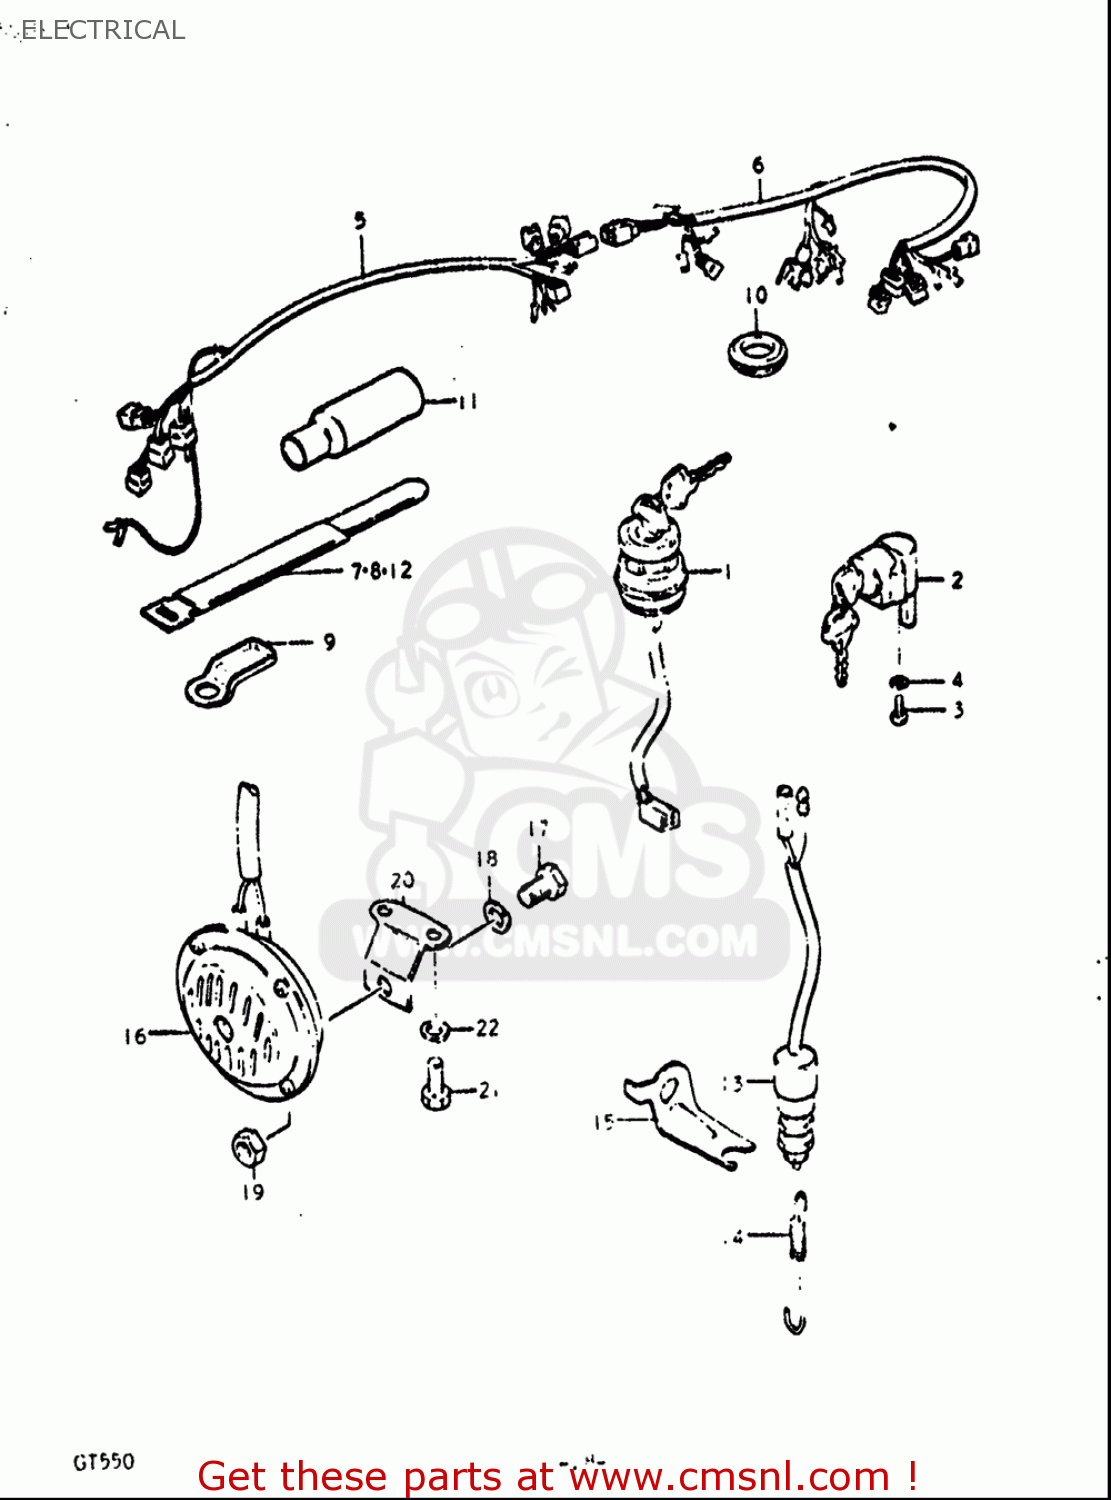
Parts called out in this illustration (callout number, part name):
1	SWITCH ASSY,IGNITION
2	LOCK ASSY,STEERING
3	SCREW
4	WASHER,LOCK
7	CLAMP
8	CLAMP
9	CLAMP
11	BOOT,WIRING HARNESS
12	CLAMP
13	SWITCH ASSY,STOP LAMP
14	SPRING
15	BRACKET, BRAKE LAMP SWITCH
17	BOLT
18	WASHER,LOCK
19	NUT
21	BOLT
22	WASHER,LOCK
